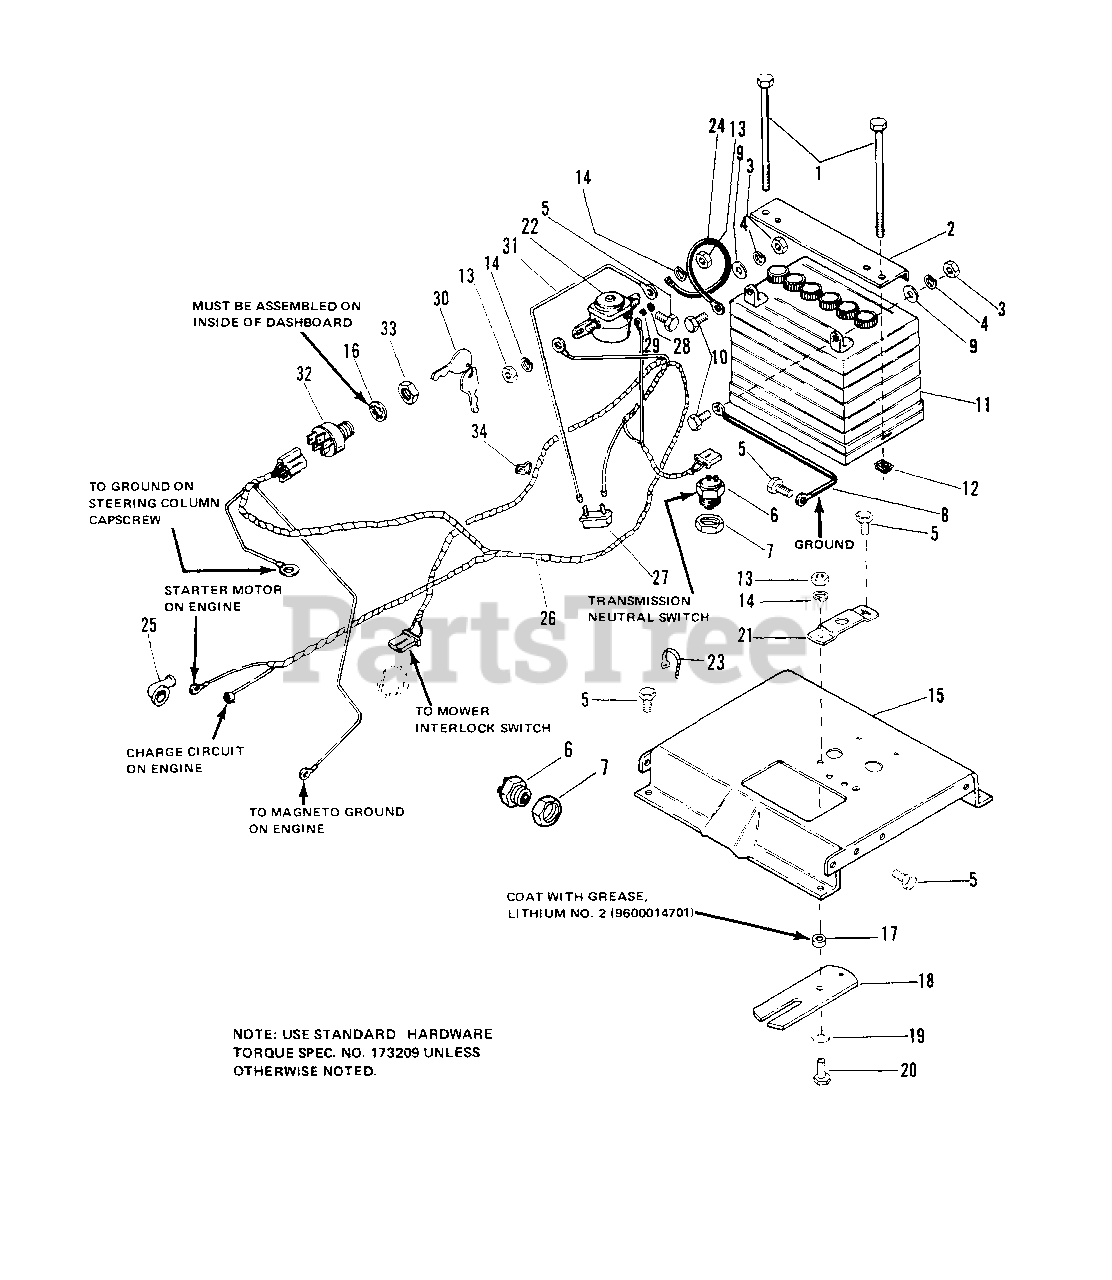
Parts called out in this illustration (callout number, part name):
1	CAPSCREW, Hex Hd., 1/4-20 x 7
2	HOLD-DOWN, Battery
3	NUT, Hex, 1/4-20
4	LOCKWASHER, Spring, 5/16
5	SCREW, Hex, Washer Hd, 1/4-20 x 3/8
6	SWITCH, Interlock
7	NUT, Lock, 9/16-18
9	WASHER, Plain, 1/4
10	CAPSCREW, Hex Hd., 1/4-20
11	BATTERY
12	NUT, Retainer, 1/4-20
13	NUT, Hex, 5/16-18
14	LOCKWASHER, Spring, 5/16
15	SUPPORT, Frame
16	LOCKWASHER, Internal Tooth, 5/8
18	LEVER, Switch
20	CAPSCREW, Hex Hd., 5/16-18 x 1
21	BRACKET, Switch
25	COVER, Terminal
26	WIRING HARNESS (1690261 Only)
26	WIRING HARNESS (1690343 Only)(05071)
26	WIRING HARNESS (1690343 Only)
27	BREAKER, Circuit
28	NUT, Hex, Machine, No. 10-32
29	LOCKWASHER, External Tooth, No. 10
30	KEYS & RING ASSY
32	SWITCH, Ignition
33	NUT, Hex, 5/8-32 (Ignition)
34	CLIP, Speed
